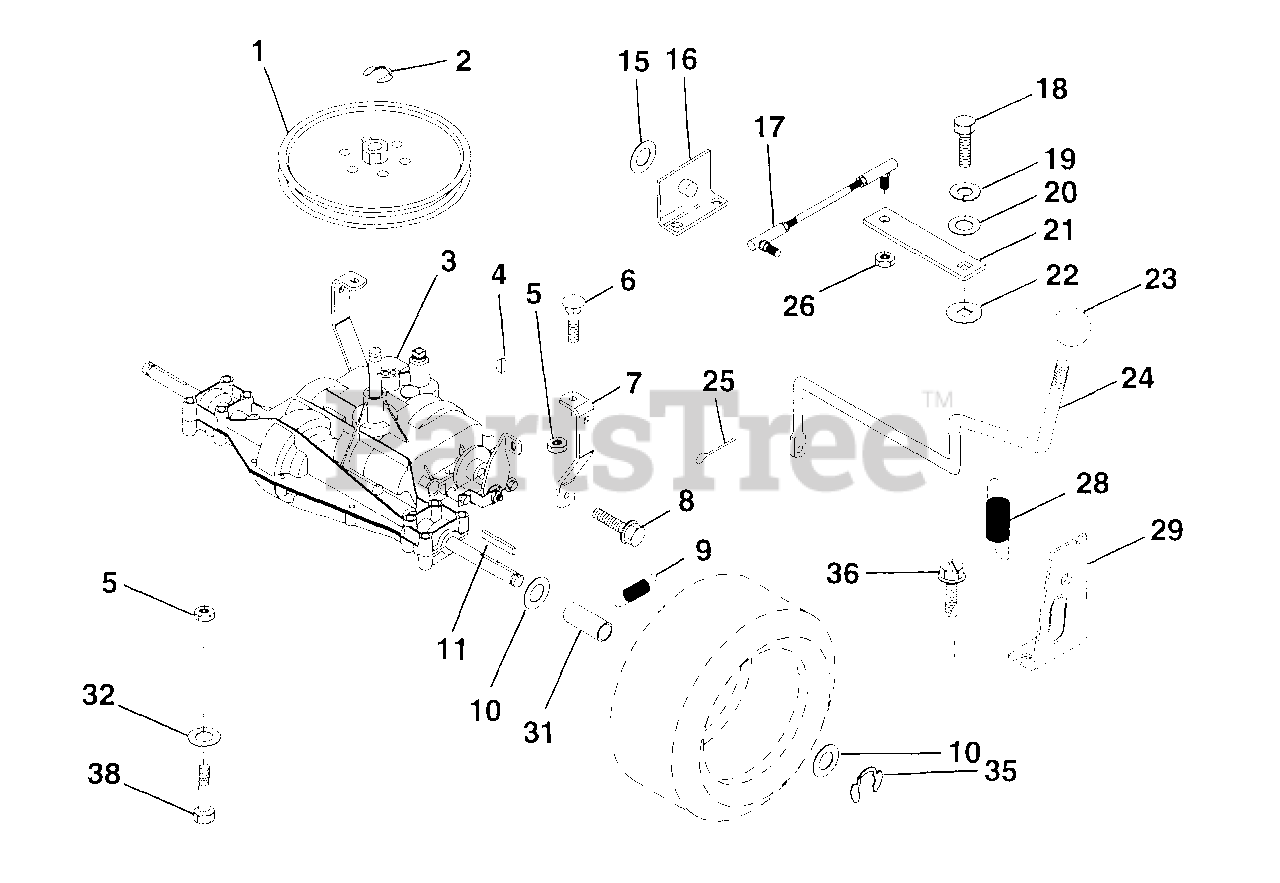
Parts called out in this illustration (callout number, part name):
2	Ring, Retainer
3	Transaxle
4	Key, Woodruff #9
5	Nut, Crownlock 5/16-18
6	Bolt, Carriage 5/16-18 UNC x 3/4
7	Strap, Torque
8	Screw 5/16-18 x 3/4
9	Spring, Brake
10	Washer 25/32 x 1-1/4 x 16 Ga.
11	Key, Square
15	Washer 17/32 x 1 x 16 Ga.
16	Support Handle Shift LH
17	Link, Shift
18	Bolt, Fin Hex 1/4-28 UNF x 3/4 Gr. 8
19	Washer, Lock 1/4
20	Washer 9/32 x 3/4 x 10 Ga.
21	Arm, Shift
22	Washer, Shift Plate
23	Knob, Rd 1/2-13
25	Pin, Cotter 1/8 x 1
26	Locknut 5/16-24 UNF
28	Extension, Spring
29	Support Handle Shift RH
31	Spacer Axle
32	Washer 11/32 x 11/16 x 16
36	Screw, Thd Cut 1/4-20 x 1/2
38	Bolt, Hex Hd 5/16-18 x 2-3/4
